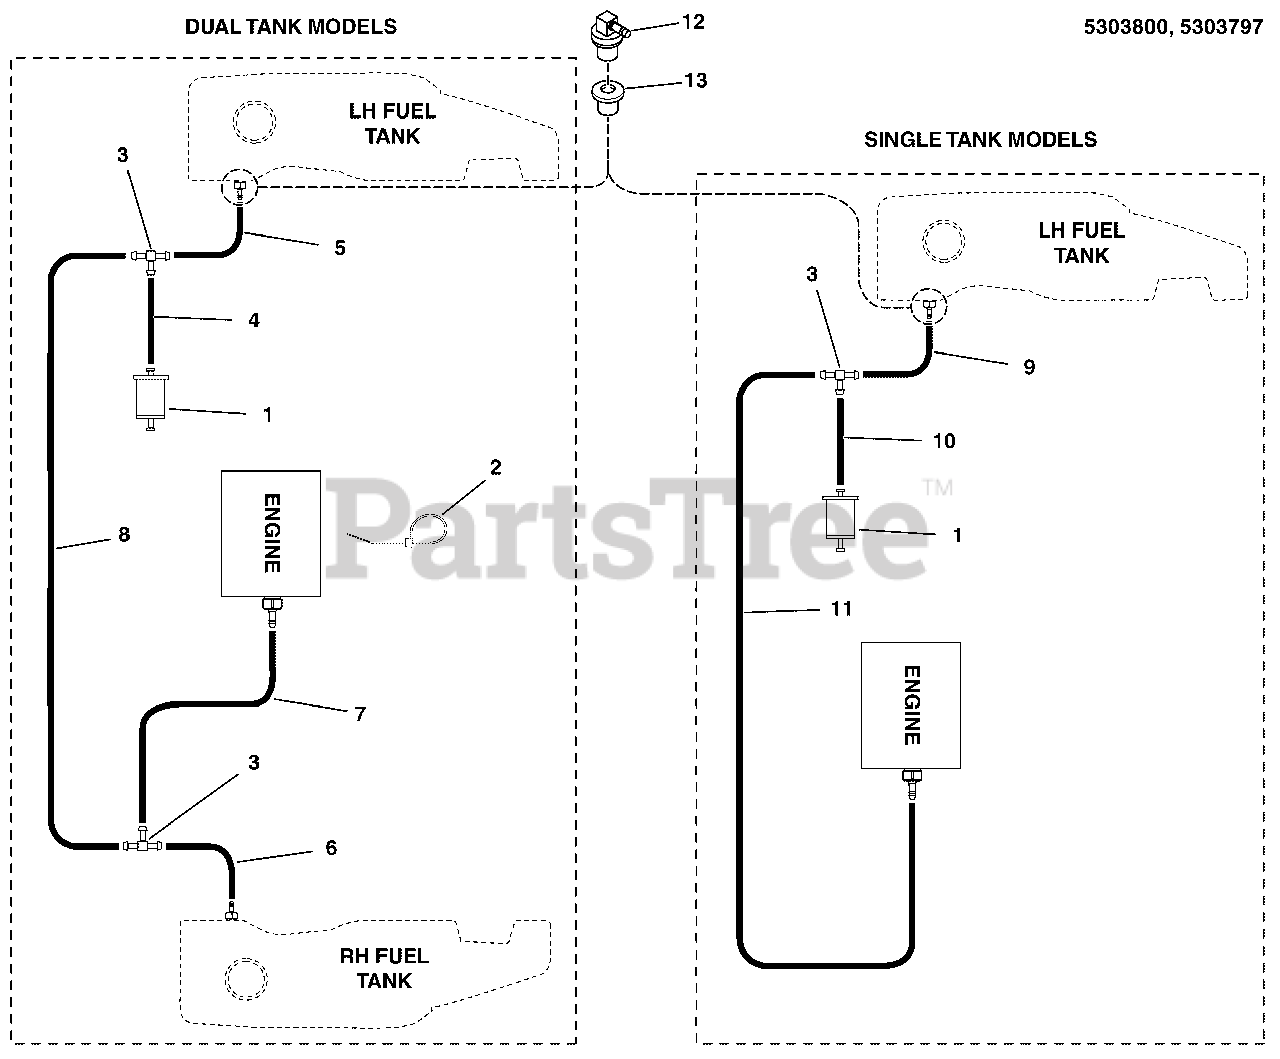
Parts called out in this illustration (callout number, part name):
1	FILTER, FUEL
2	TIE,SELF-LOCKING, 6"
3	FITTING, 3/16" TEE, BARB TYPE, HDPE
4	HOSE, VAPOR, 5MM ID, 2.00 LG
5	HOSE, VAPOR, 5MM ID, 21.50 LG
6	HOSE, VAPOR, 5MM ID, 39.00 LG
7	HOSE, VAPOR, 5MM ID, 5.00 LG
8	HOSE, VAPOR, 5MM ID, 24.00 LG
9	HOSE, VAPOR, 5MM ID, 41.00 LG
10	HOSE, VAPOR, 5MM ID, 2.00 LG
11	HOSE, VAPOR, 5MM ID, 20.00 LG
12	REMOTE, VENT ASSEMBLY, NO VALVE
13	GROMMET
